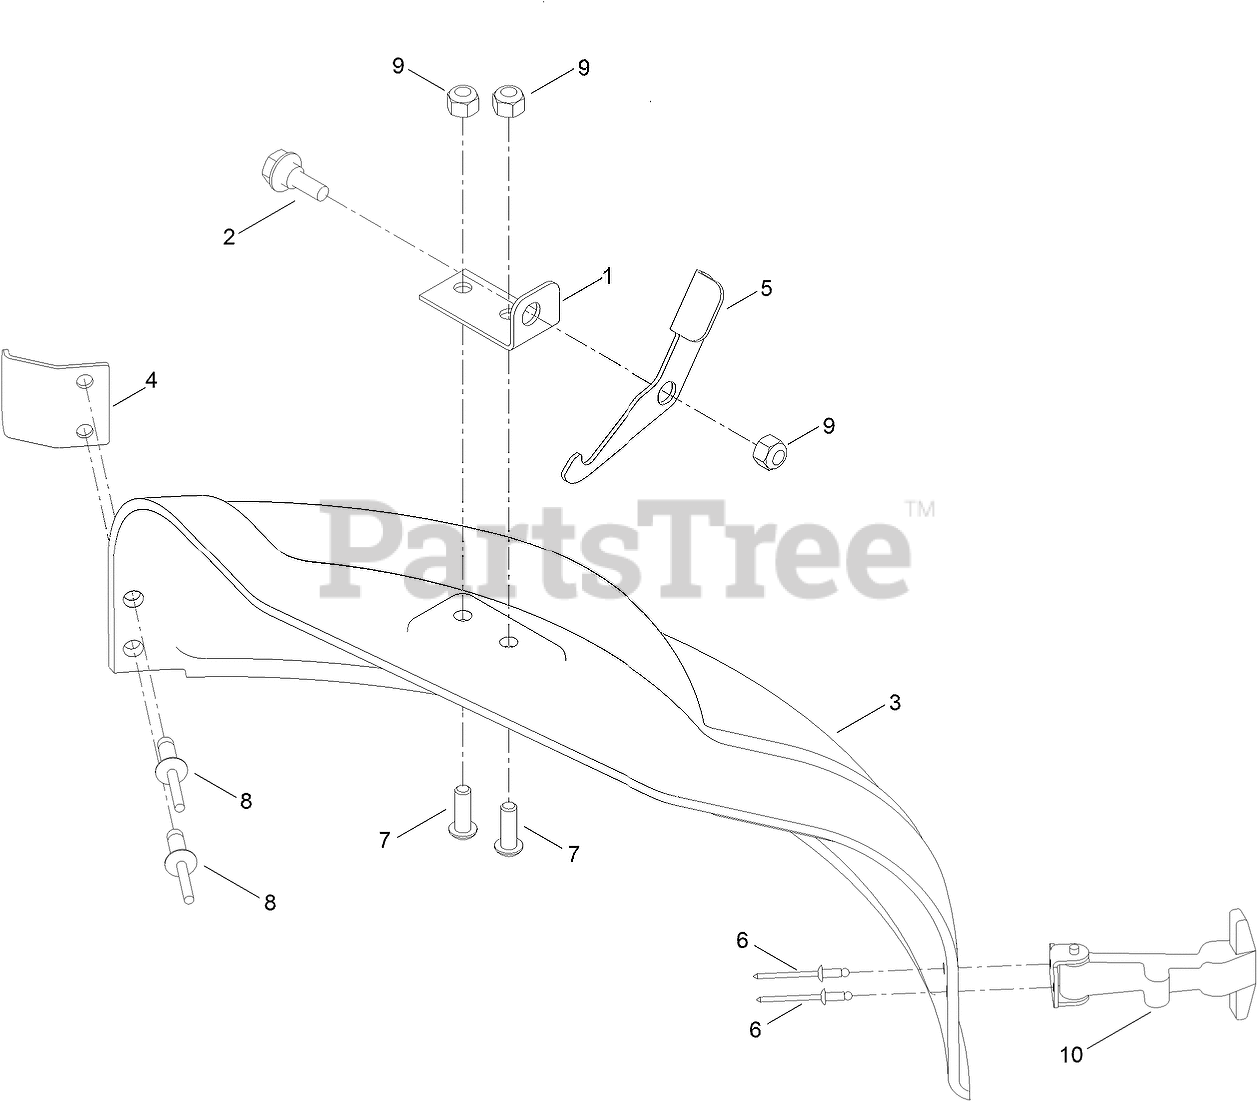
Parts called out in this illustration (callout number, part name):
1	PLATE-PIVOT
3	PLUG-MULCH, 42 INCH
4	BRACKET-ELBOW
6	RIVET-POP
7	SCREW-HSBH
8	RIVET-BLIND
9	NUT-HEX
10	HANDLE ASM
